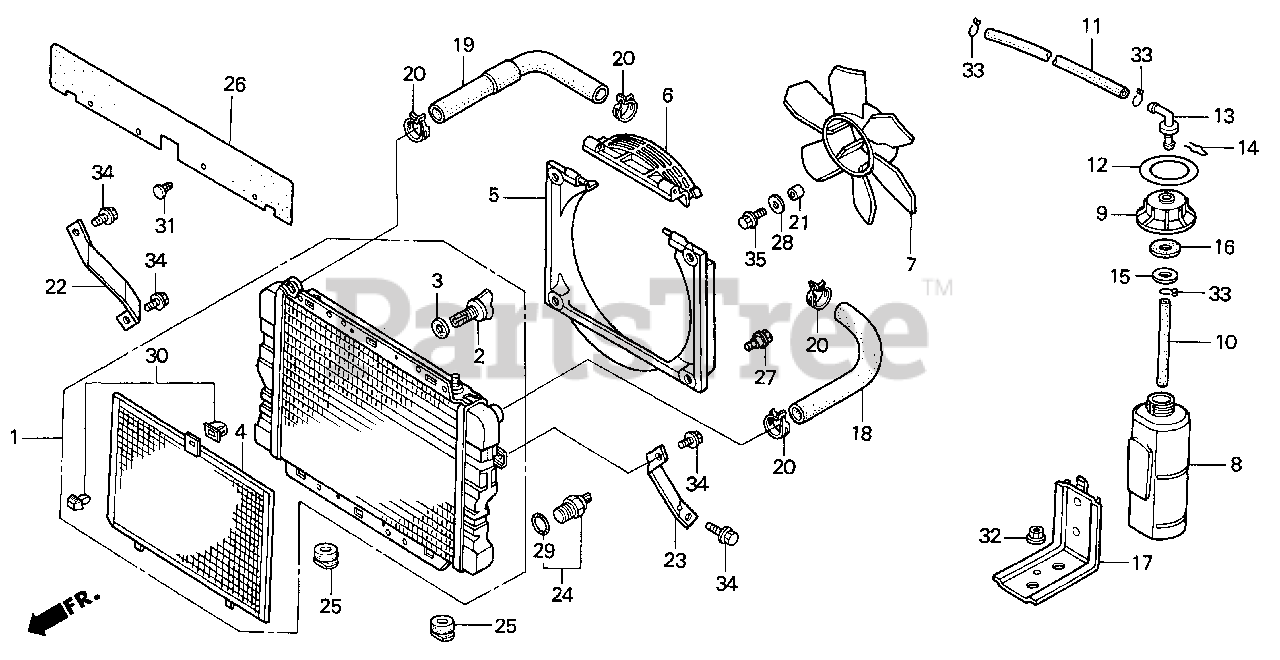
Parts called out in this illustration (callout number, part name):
1	RADIATOR ASSY.
2	VALVE, DRAIN (TOYO)
3	GASKET, DRAIN (TOYO)
4	SCREEN, FR.
5	SHROUD, RADIATOR (LOWER)
6	SHROUD, RADIATOR (UPPER)
7	FAN, COOLING
8	TANK, RESERVE
9	CAP, RESERVE TANK
10	HOSE, RESERVE TANK
11	TUBE, RESERVE TANK
12	MARK, RESERVE TANK
13	JOINT, RESERVE TANK
14	CLIP, RESERVE TANK JOINT
15	WASHER, RESERVE TANK
16	GASKET, RESERVE TANK
17	BRACKET, RESERVE TANK
18	HOSE A, WATER
19	HOSE B, WATER
20	CLIP, WATER HOSE
21	COLLAR, FAN
22	PLATE, R. RADIATOR HOLDER
23	PLATE, L. RADIATOR HOLDER
24	SWITCH ASSY., THERMO
25	RUBBER B, BATTERY BOX
26	SEAL, RADIATOR (UPPER)
27	BOLT, BUMPER
28	WASHER, PLAIN (6.5X15)
29	O-RING (13.5X1.4)
31	CLIP, TRIM (5MM) *NH1L* (BLACK)
32	NUT, FLANGE (8MM)
33	CLIP, TUBE (C11)
34	BOLT, FLANGE (6X12)
35	BOLT, FLANGE (6X16)
